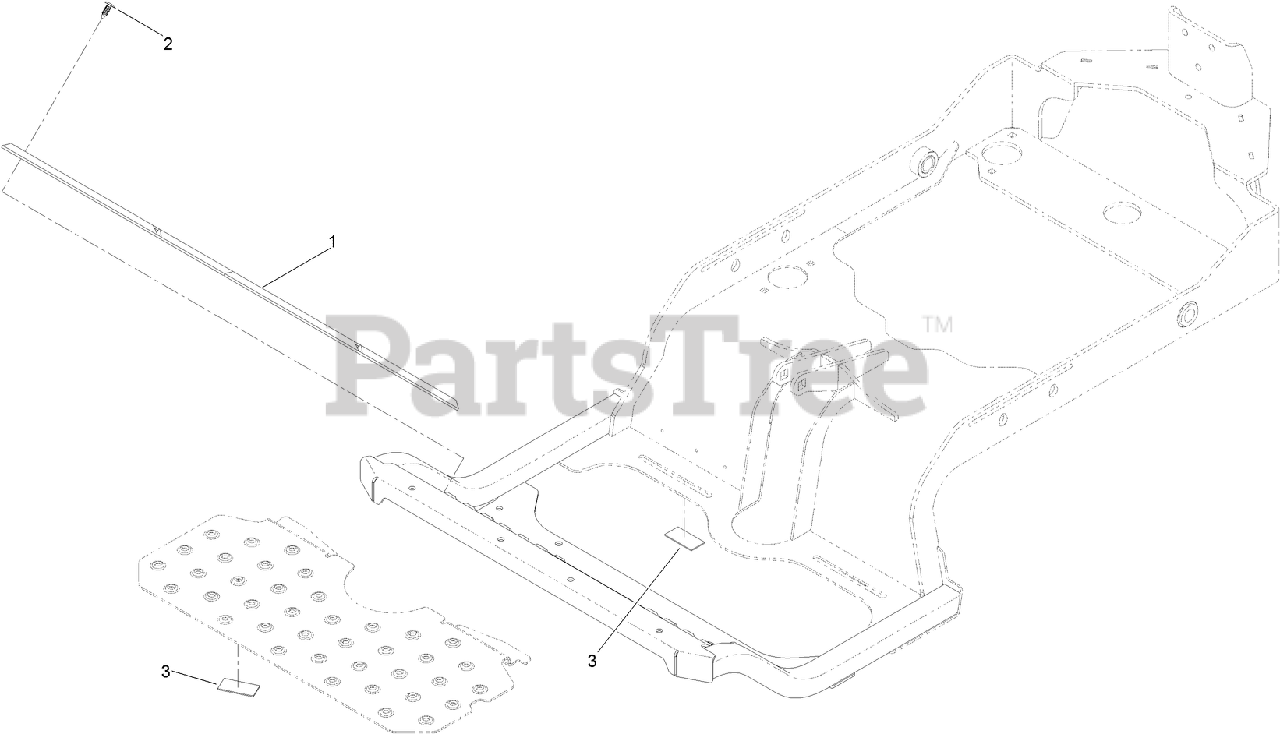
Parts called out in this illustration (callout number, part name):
1	MAT-FLOOR
2	PLUG-PLASTIC
3	PAD-RUBBER
